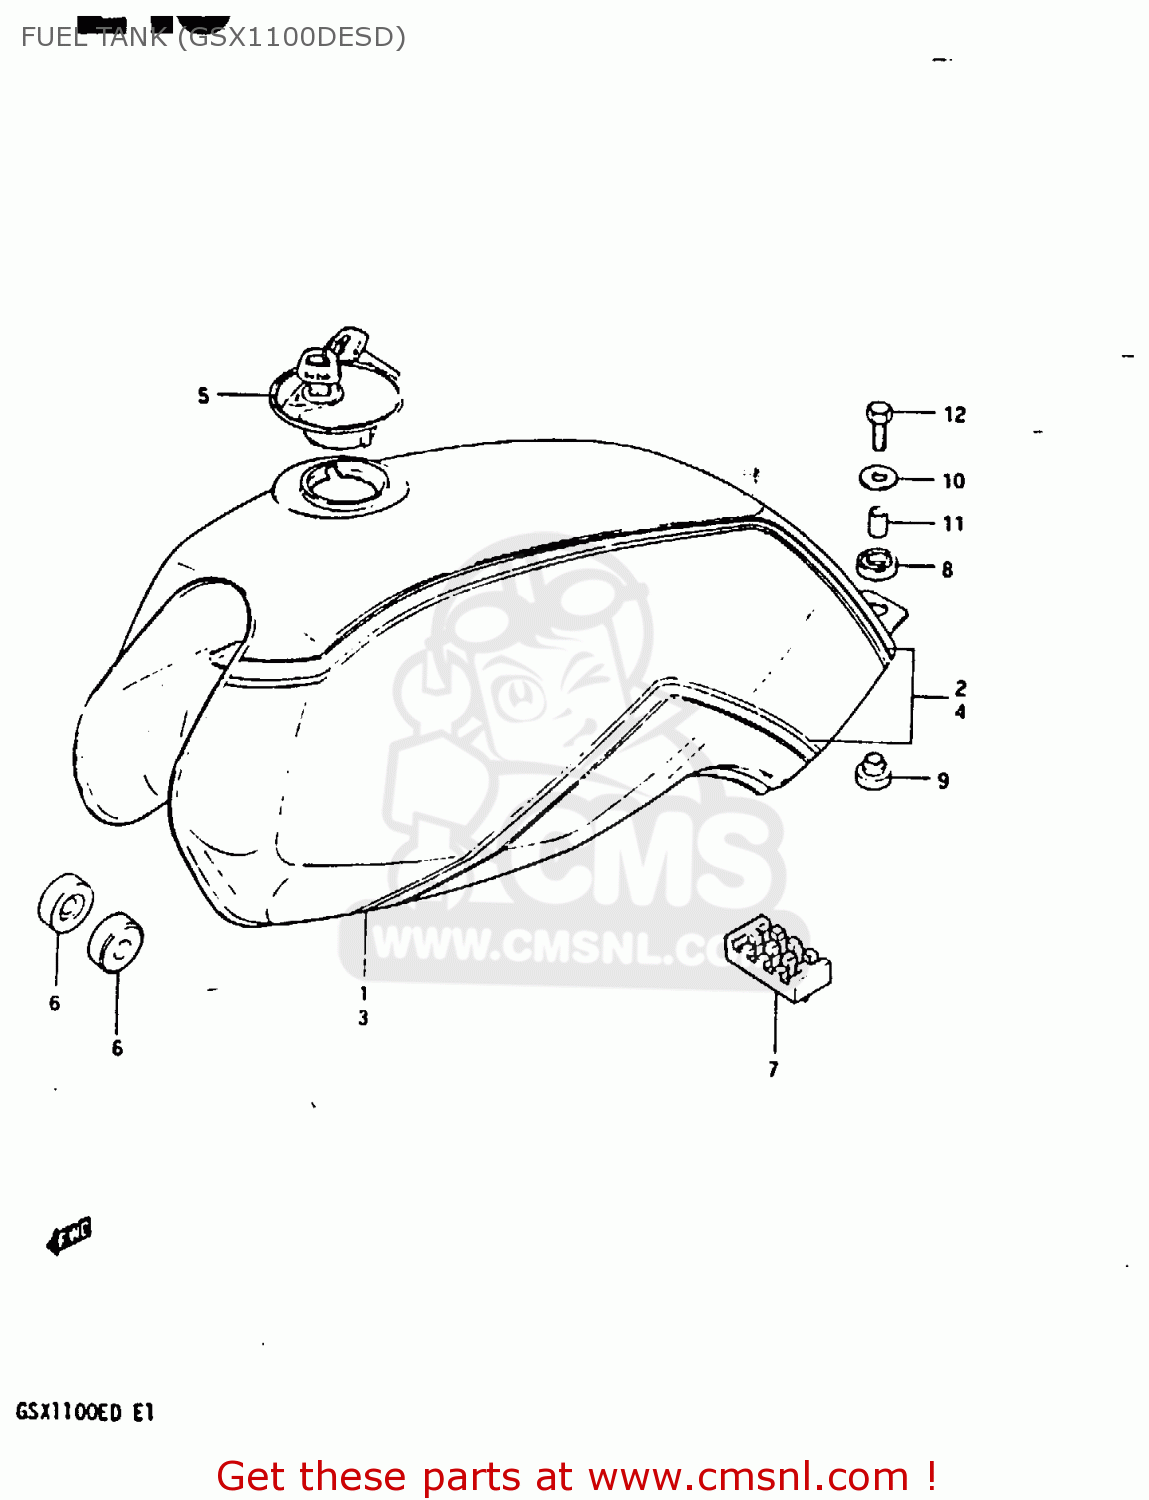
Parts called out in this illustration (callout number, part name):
1	TANK ASSEMBLY,FUEL
2	TAPE SET,FUEL TANK
3	TANK ASSEMBLY,FUEL
4	TAPE SET,FUEL TANK
5	CAP SET,FUEL TANK
6	CUSHION
7	CUSHION,FUEL TANK CTR
8	CUSHION
9	CUSHION
10	WASHER (6.5X24X1.6)
11	SPACER
12	BOLT
